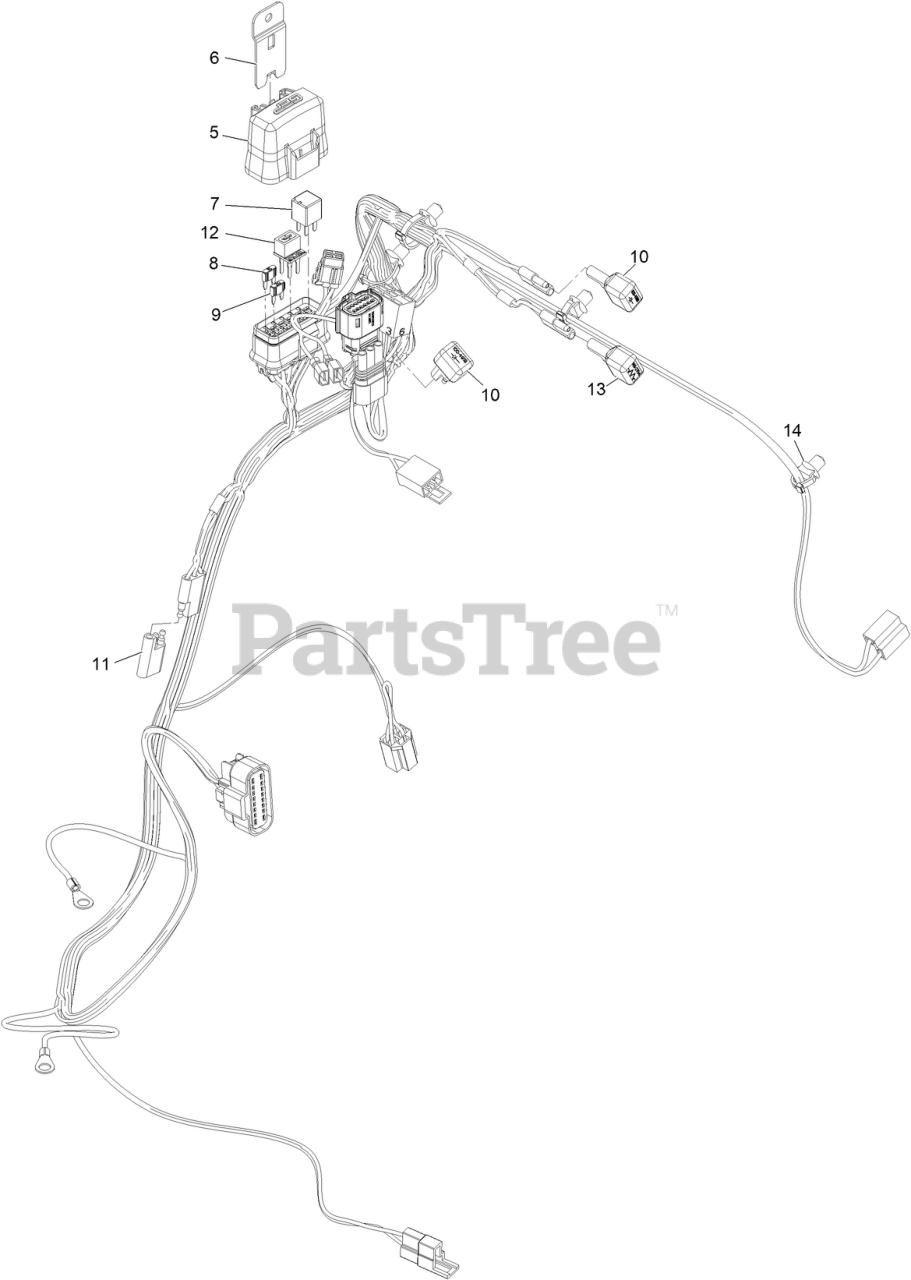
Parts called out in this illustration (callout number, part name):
5	COVER-BLOCK, FUSE
6	CLIP-MOUNTING
7	RELAY-MICRO
8	FUSE-MINI BLADE, 15 AMP
9	FUSE-MINI BLADE, 20 AMP
11	Cap-Plug
12	RELAY-ENGINE IDLE, 10K
13	RESISTOR - 13.7K OHMS 1W 1% OVERMOLDED
14	CLIP-TIE
